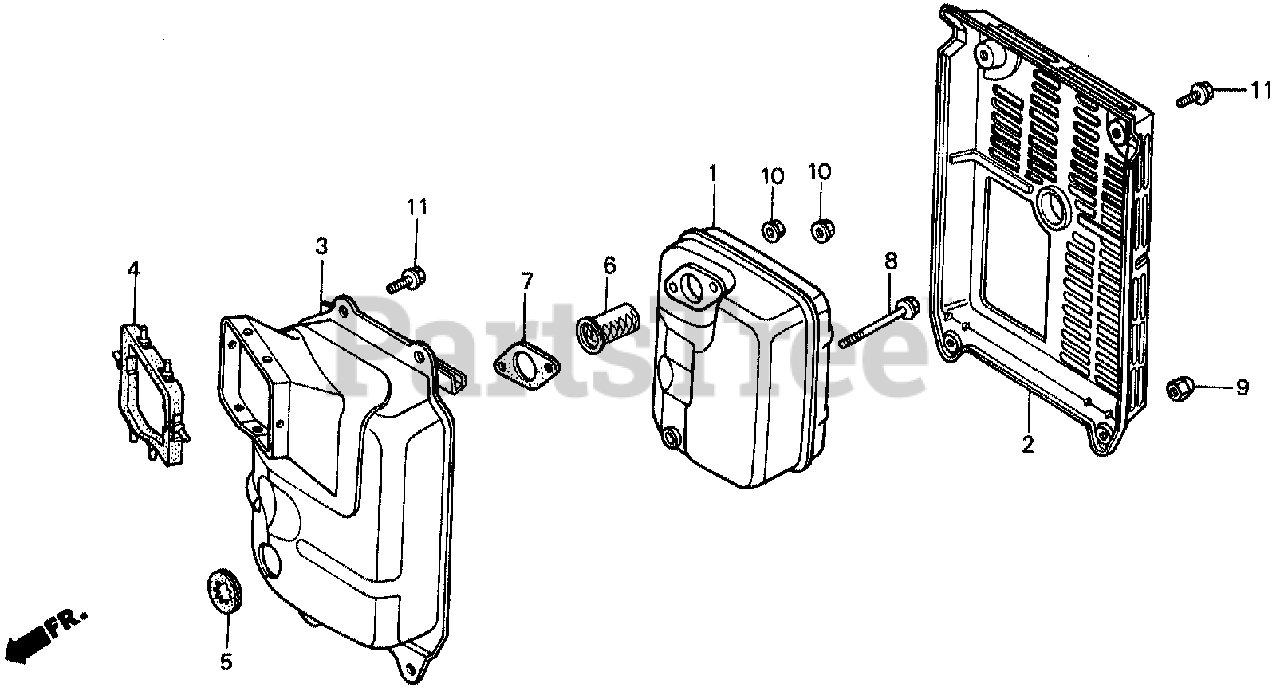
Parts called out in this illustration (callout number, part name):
1	MUFFLER
2	PROTECTOR, MUFFLER (OUTER) *NH105* (MAT BLACK)
3	PROTECTOR, MUFFLER (INNER)
4	RUBBER, PROTECTOR (INNER)
5	SEAL B, MUFFLER PROTECTOR
6	ARRESTER KIT, SPARK
7	GASKET, MUFFLER
8	BOLT, FLANGE (6X80)
9	NUT, CAP (6MM)
10	NUT, FLANGE (6MM)
11	BOLT, FLANGE (6X10)
